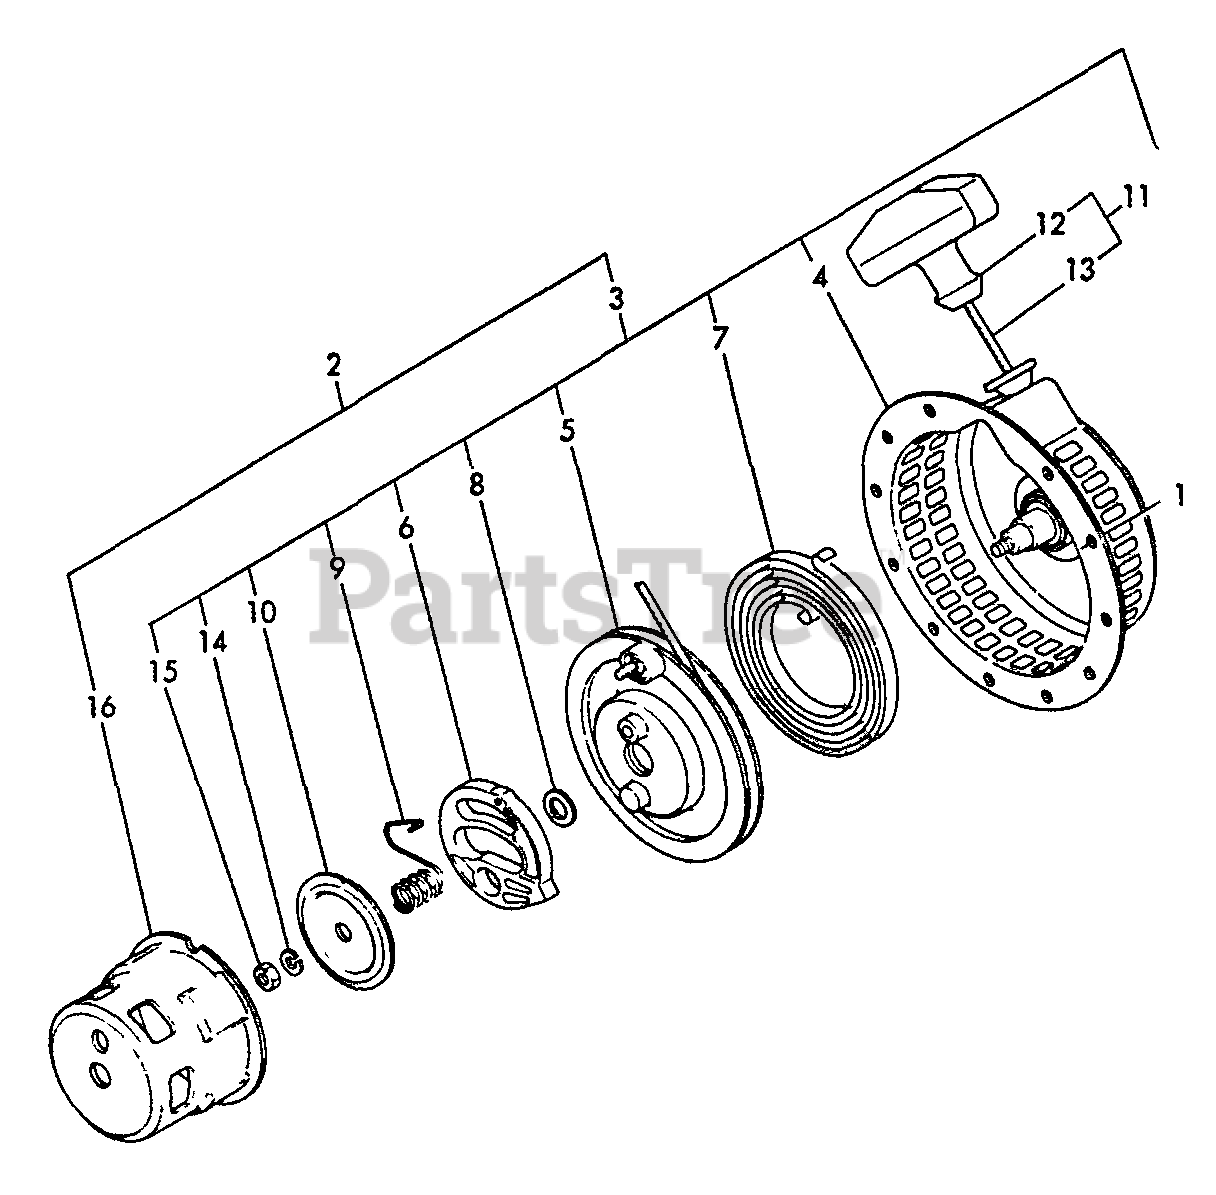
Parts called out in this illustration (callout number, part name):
1	BOLT - 6X12 -- PLATED
2	STARTER ASSY
3	STARTER ASSY
4	CASE, STARTER
5	PULLEY
8	WASHER, THRUST
9	SPRING, FRICTION
10	PLATE, FRICTION
11	STARTER ROPE ASSY
12	GRIP, STARTER
13	ROPE, STARTER
14	LOCKWASHER - 6
15	NUT - 6
16	REEL, ROPE
